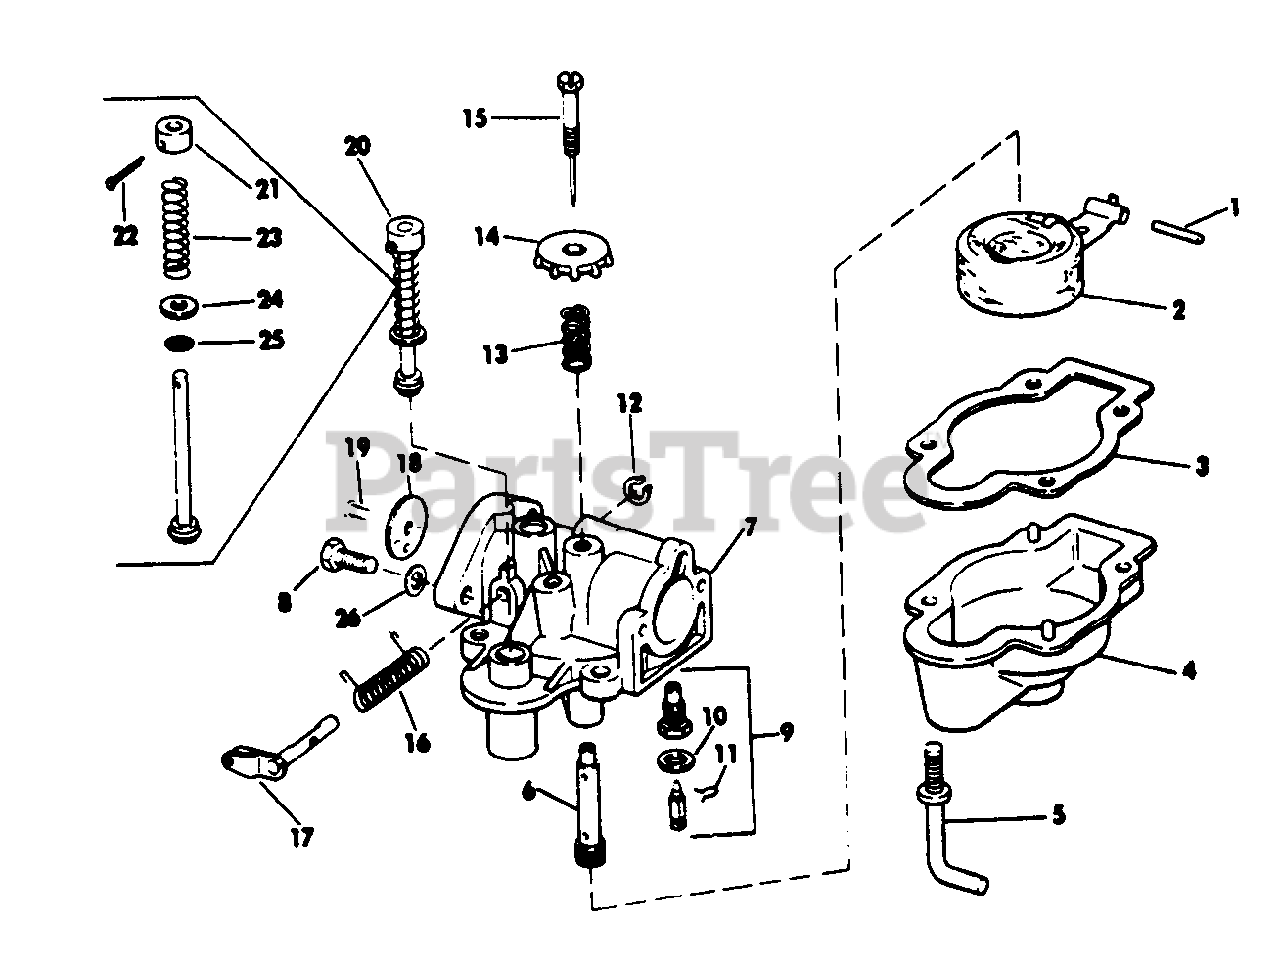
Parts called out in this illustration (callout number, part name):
1	Pin-Float Arm Hinge
2	Float and Arm Assy.
3	Gasket-Float Chamber
4	Chamber-Float
5	Screw-Float Chamber
6	Nozzle
7	Carburetor Body Assembly
9	Float Valve and Seat Assy
11	Clip
12	Grip Ring
13	Spring-Needle Adjustment
14	Knob-Needle Adjustment
15	Needle Assy.
16	Spring-Throttle
17	Throttle Shaft and Lever Assy.
18	Disc-Throttle
19	Screw-Throttle Shaft Disc.
20	Primer Assembly
21	Knob-Primer
22	Cotter Pin
23	Spring-Compression
24	Washer-Plain
25	"O" Ring
